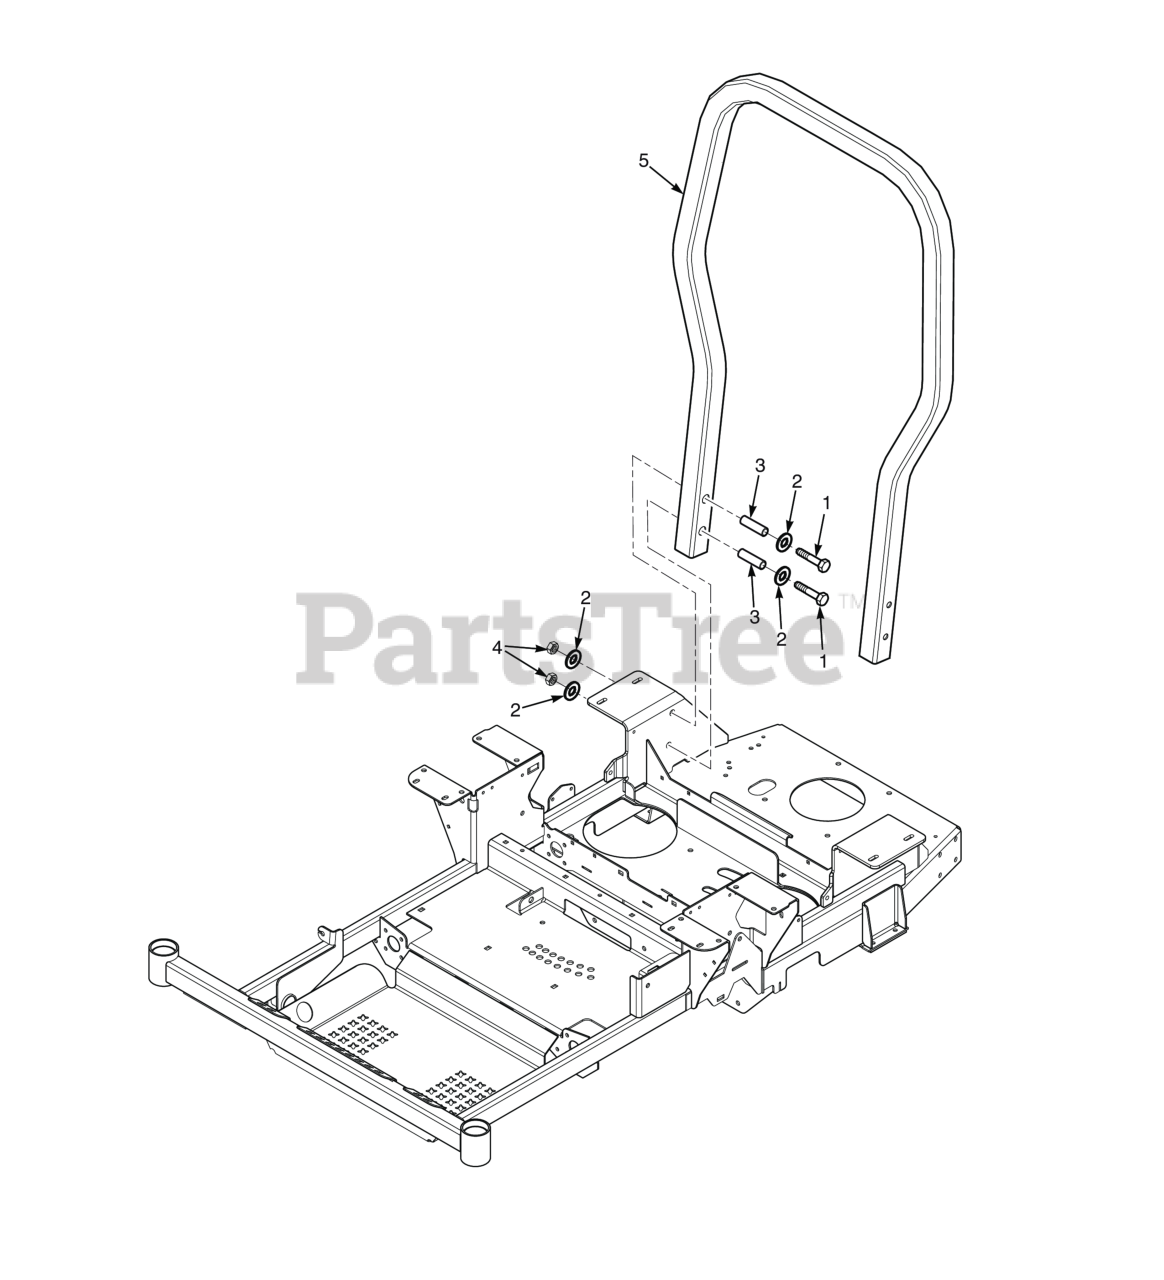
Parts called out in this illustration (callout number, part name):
1	Bolt, Hex Head 1/2-13 x 3-1/4" Gr. 8
2	Flatwasher, 1/2 - .531 x 1.062 x .095
3	Bushing, SFZ ROPS
4	Locknut, Hex 1/2-13 Center Lock
5	ROPS, SFZ48, SFZ52
